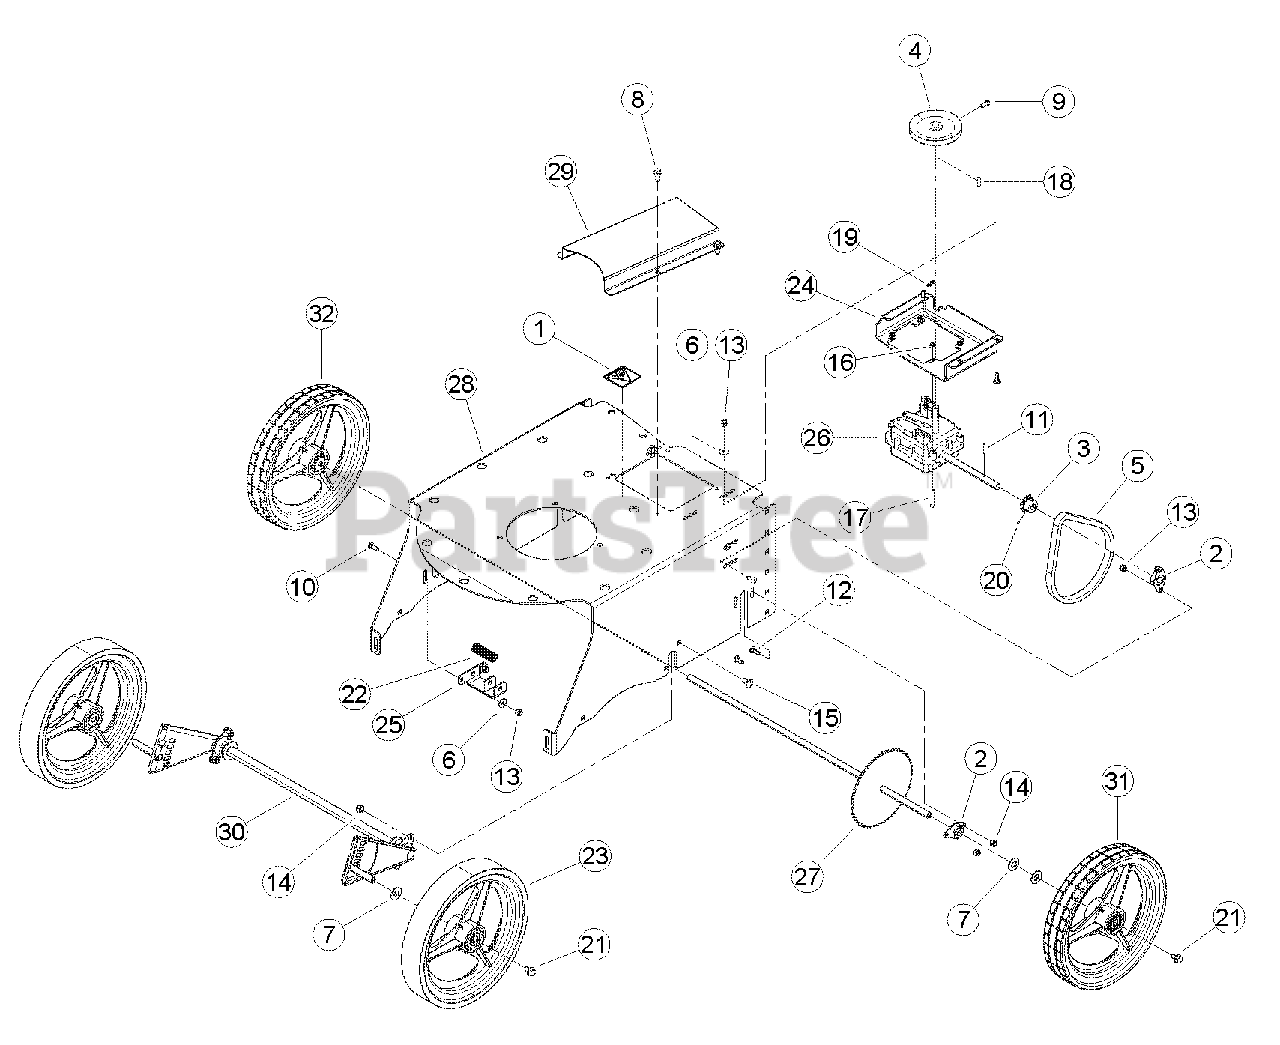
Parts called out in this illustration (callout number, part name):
1	DECAL, SHIELD DANGER
2	BEARING, 1/2 FLANGE
3	SPROCKET, 35 B10
4	PULLEY, 4 O.D. X 12 MM BORE
5	CHAIN, #35 X 62 PITCH W/ CONN. LINK
6	WASHER, 1/4 FLAT
7	WASHER, 1/2 SAE FLAT
8	SCREW, 11/32 X 7/8 HWH AB THREAD
9	SCREW, 1/4 X 5/8 SQ HD SET
10	BOLT, 1/4 X 3/4 CRG
11	PIN, 1/8 X 7/8 SPRING
12	BOLT, 1/4 X 5/8 CRG
13	NUT, 1/4 NYLOCK
14	NUT, 5/16 NYLOCK
15	BOLT, 5/16 X 5/8 CRG
16	NUT, #10 X 24 NYLOCK
17	SCREW, #10 X 24 X 1-1/2 PAN PHP ZP
18	KEY, 4 MM SP X 20 MM
19	WASHER, #6 SAE FLAT
20	SCREW, #8-32 X 3/16 KNR CUP PT
21	BOLT, 5/16-18 X 1/2 GR5 HH SER/FLN
22	SPRING, COMPRESS LC-072J-6
23	WHEEL ASSEMBLY, BEARVAC PUSH
24	WELDMENT, TRANSMISSION MOUNT
25	WELDMENT, BEARVAC HEIGHT ADJ.
27	WELDMENT, SP LONG AXLE
28	SUPPORT, BEARVAC FRAME
29	GUARD, BEARVAC BELT
30	WELDMENT, AXLE PIVOT
31	WHEEL, BEARVAC SP LEFT
32	WHEEL, BEARVAC SP RIGHT
